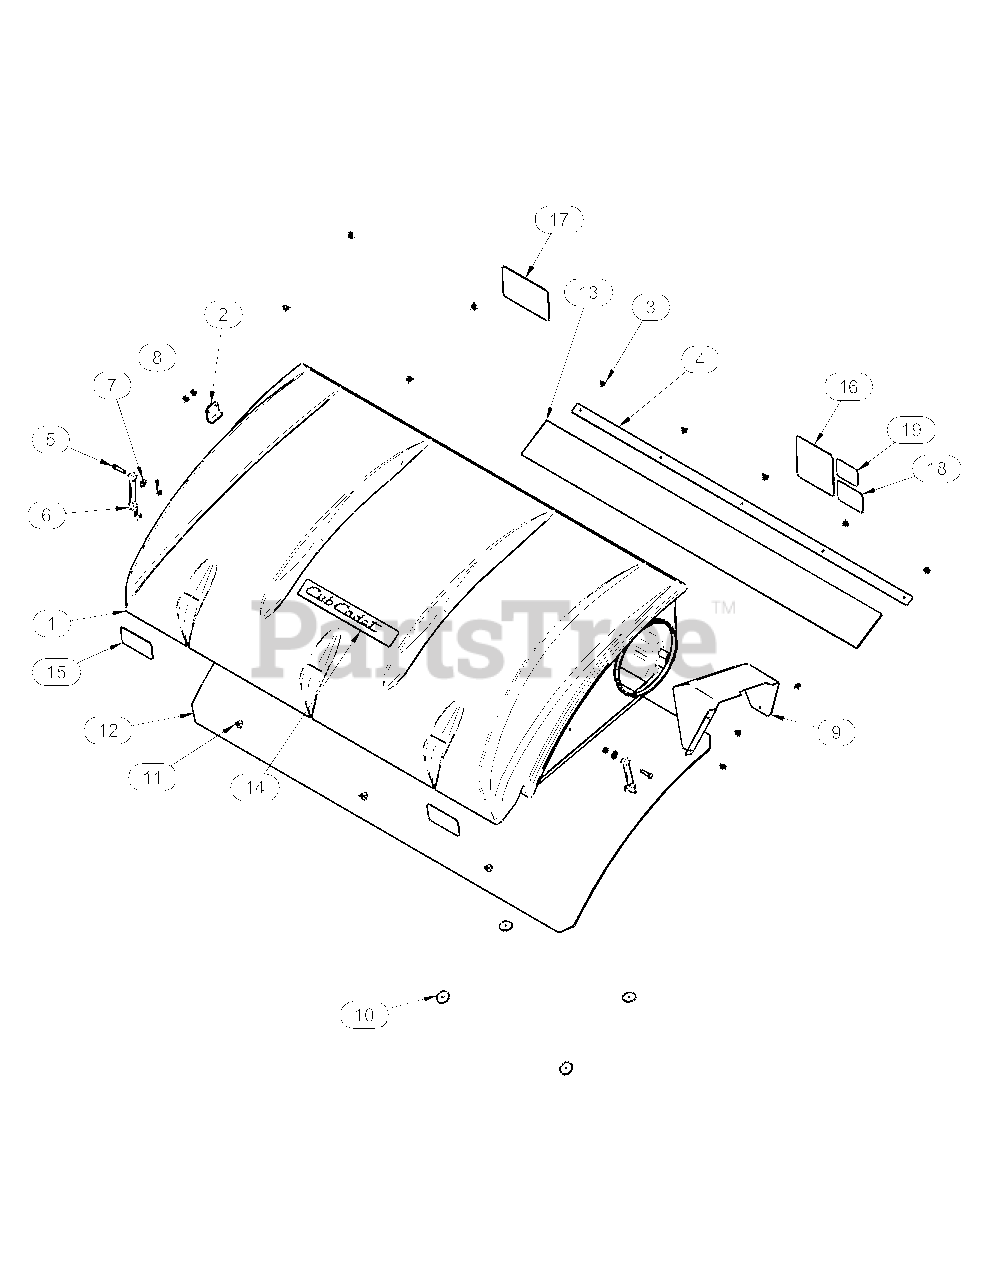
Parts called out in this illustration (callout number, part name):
1	PRO 3 BAGGER TOP
2	HINGE STOP PLATE
3	RIVET-PLASTIC 5MM
4	DUST GUARD BRACE
5	BOLT-1/4-20 X 1-1/
6	RUBBER STRAP W/HOO
7	WASHER-FLAT
8	NUT-NYLOCK 1/4-20
9	GRASS DEFLECTOR
10	WASHER-FENDER 3/16
11	FLAT HEAD FASTENER
13	DUST GUARD
14	LOGO-CUB CADET
15	LABEL-2 X 4 RED RE
16	LABEL-WARNING
17	DECAL-MADE IN AMER
18	DECAL-TUBE WEAR
19	DECAL-WARNING
